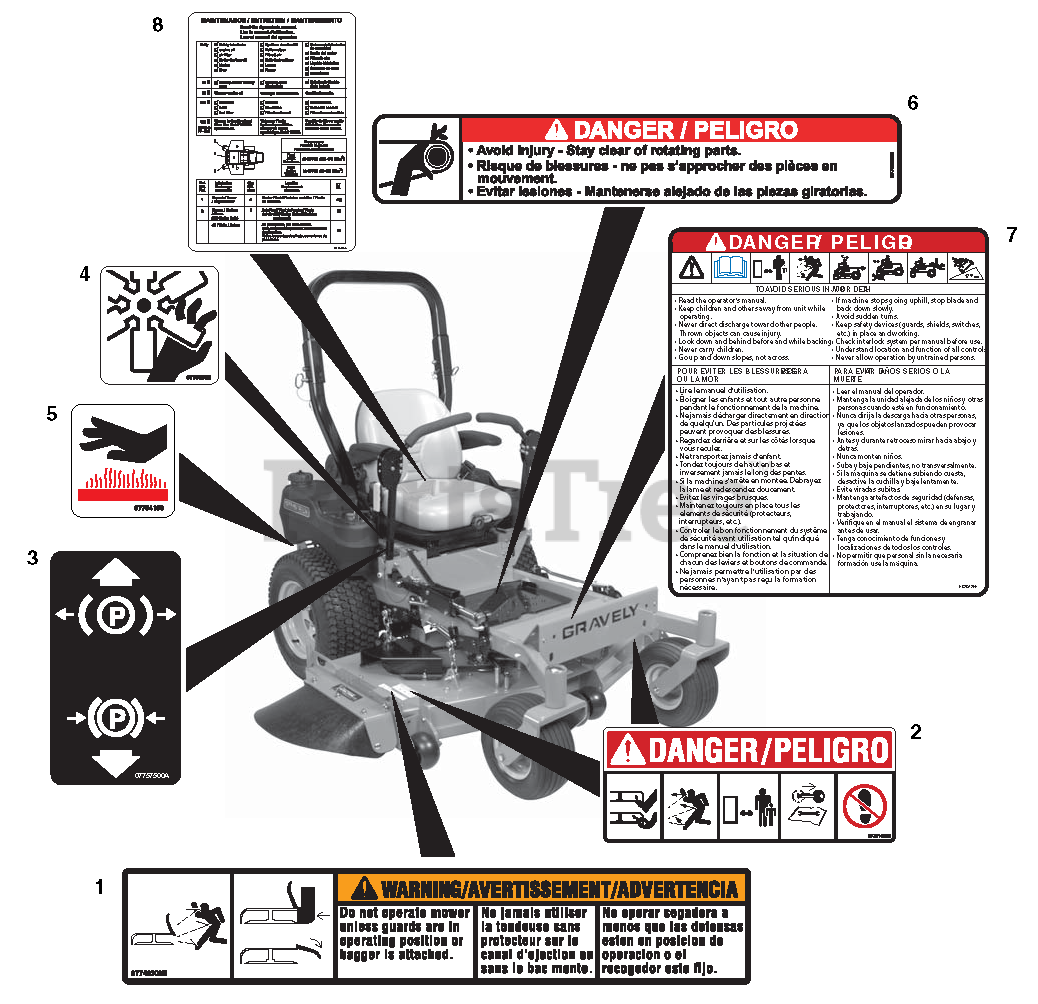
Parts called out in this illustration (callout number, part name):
1	DECAL, WARNING
2	DECAL, MOWER PAN DANGER
3	DECAL, PARKING BRAKE LEVER
4	DECAL, DANGER FAN
5	DECAL, HOT SURFACE
6	DECAL- DANGER
7	DECAL, DANGER - BILINGUAL
8	DECAL-MAINTENANCE INSTRUCTIONS
